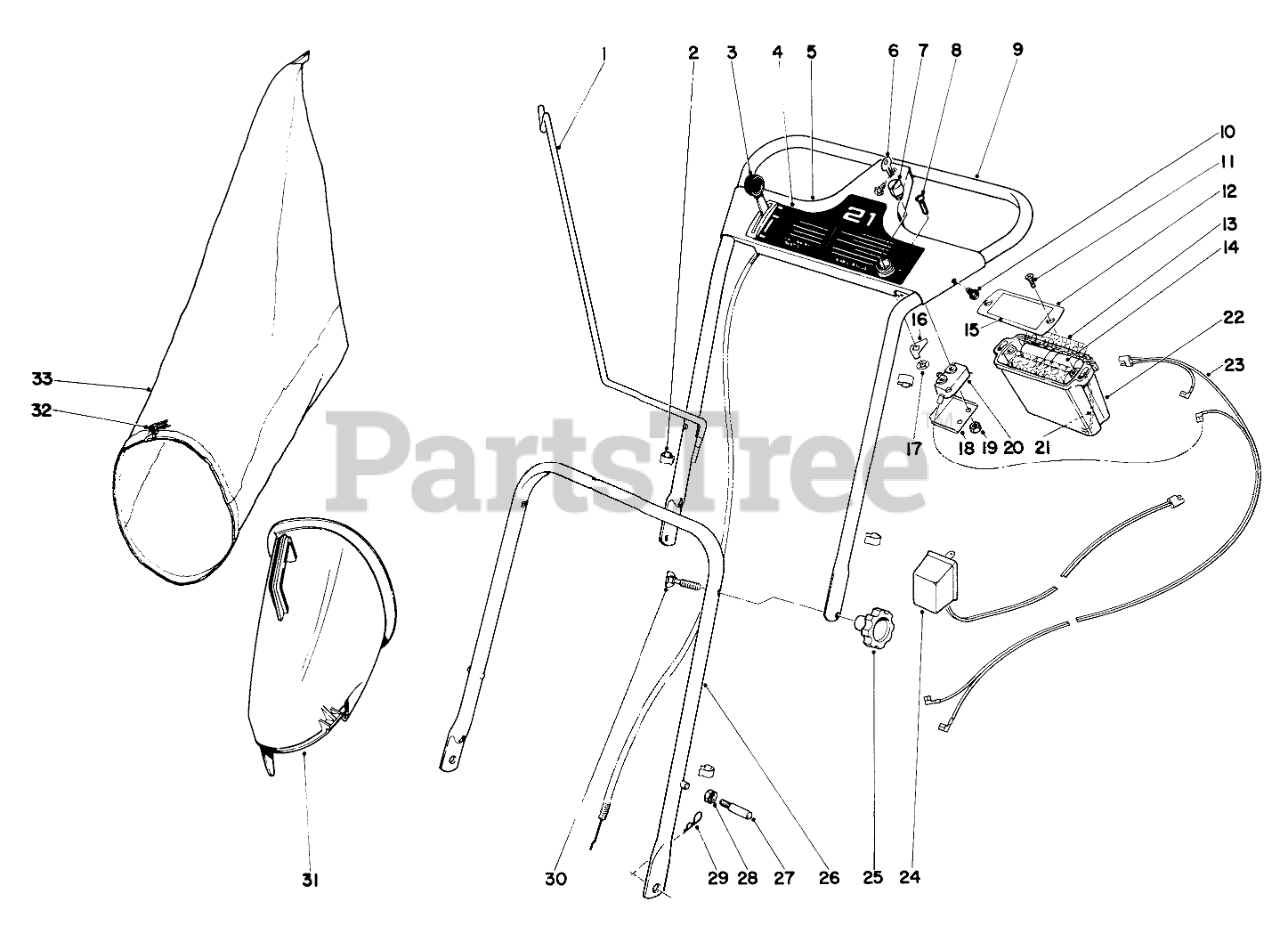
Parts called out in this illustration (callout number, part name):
1	Bag Hanger Rod
2	CONTROL WIRE CLIP
3	Throttle Control
4	Decal, Escutcheon Plate
5	Escutcheon Plate
7	Key Hsg.
9	Upper Handle
10	SCREW-HWHTF
12	Cover
13	Spacer
14	Battery Pack
15	Decal
18	Cover Switch
19	NUT-KEPS
20	Switch
21	Plug & Wire
22	Container Pack
23	Wire Harness
24	Charger
25	Handle Release Knob
26	Lower Handle
27	Handle Pin
28	Nut
29	PIN-COTTER, HAIR
30	HANDLE SCREW
31	Bag Attachment
32	BAG CORD FASTENER
33	Grass Bag Kit
